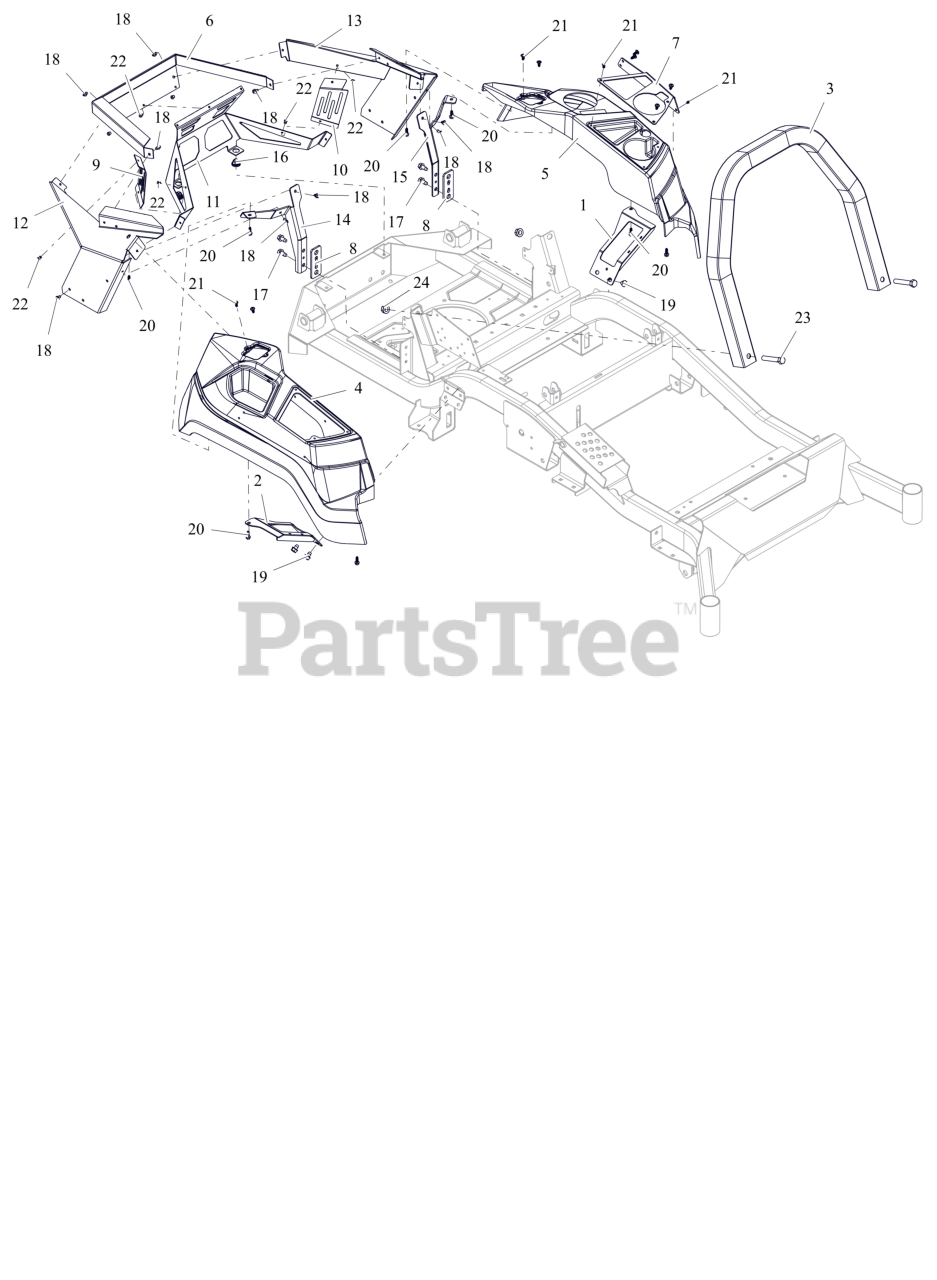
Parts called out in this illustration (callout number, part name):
1	WLDMT, LH FENDER MOUNT
2	WLDMT, RH FENDER MOUNT
3	GUARD, ENGINE -TOP (ORANGE)
4	FENDER, RH APEX - 2017
5	FENDER, LH APEX
6	GUARD,ENGINE WRAP
7	PLATE, APEX CUP HOLDER COVER
8	PLATE, CONTROL PANEL SPACER
9	SHIELD,RH ENGINE GUARD VALVE
10	SHIELD,LH ENGINE GUARD VALVE
11	GUARD, ENGINE
12	PANEL, RH REAR FENDER MOUNT
13	PANEL, LH REAR FENDER MOUNT
14	BRKT, RH FENDER MTG (ORANGE)
15	BRKT, LH FENDER MOUNT (ORANGE)
16	GROMMET, 10MM BOLLHOFF
17	SCR,TAP .375-16X.75 HWH TR ZCC
18	SCR,TAP .25-20X.375 HWH TR ZCC
19	SCR,TAP .375-16X.50 HWH TR ZCC
20	SCR, PLASTITE .25-10X.75 ZCC
21	SCR-PAN .25-15X.50 6L H/LZB500
22	RIVET, .1875 AL/AL .126-.250
23	BLT, HEX .50-13X3.00 G5 ZCC
24	NUT-LK-CTR-FLG .500-13 GG ZCC
